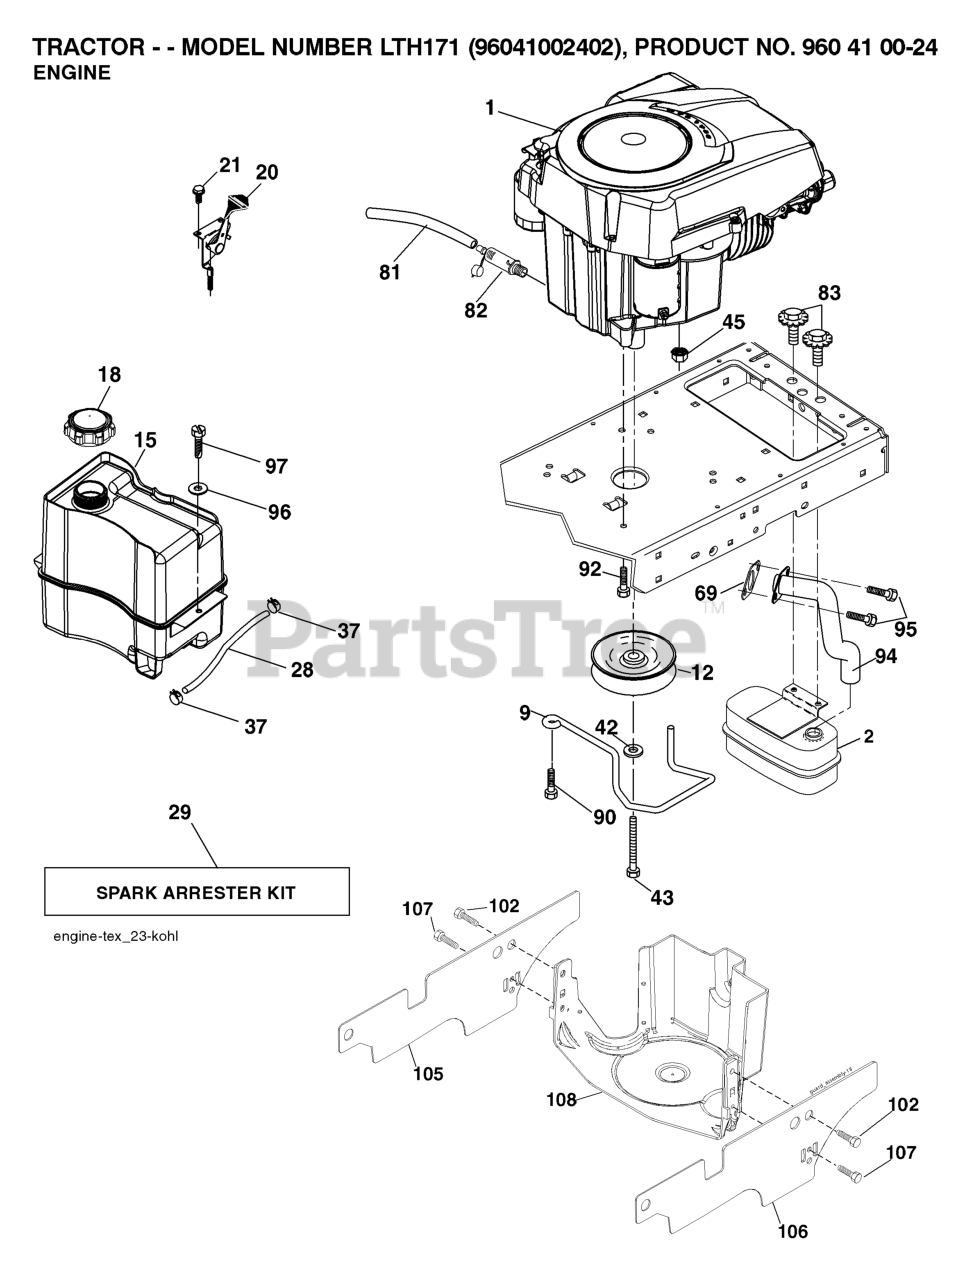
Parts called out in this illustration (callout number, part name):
2	MUFFLER.SINGLE.CYL.KOHL/B&S
9	KEEPER.BELT.ENGINE.4.2
12	PULLY ENGINE
15	RP TANK FUEL FRT 1.5 GAL
18	FUEL CAP
20	CONTROL.TH/CK.C.
21	SCREW
28	LINE.FUEL.20
29	KIT.SPARK ARRESTOR 794945 B&S
37	HOSE CLAMP
42	LOCKWASHER
43	BOLT HEX 7/16-20X4-1/4"
45	NUT
81	TUBE, DRAIN OIL ASM.
82	PLUG DRAIN OIL EASY
83	BOLT.5/16-18UNCX3/4 W/SEMS.BLK
90	SCREW 3/8-16X1
92	SCREW 3/8-16X1
94	RP.TUBE.EXHAUST.KOHL.COURAGE
95	SCREW.SOCKET HD.5/16-1
97	SCREW HEXWSHR 1/4-20X3/4
102	SCREW
105	SHIELD.SIDE.LH.3842"TEX FRENCH
106	SHIELD.SIDE.RH.3842"TEX FRENCH
107	SCREW.1/4-20X5/8
